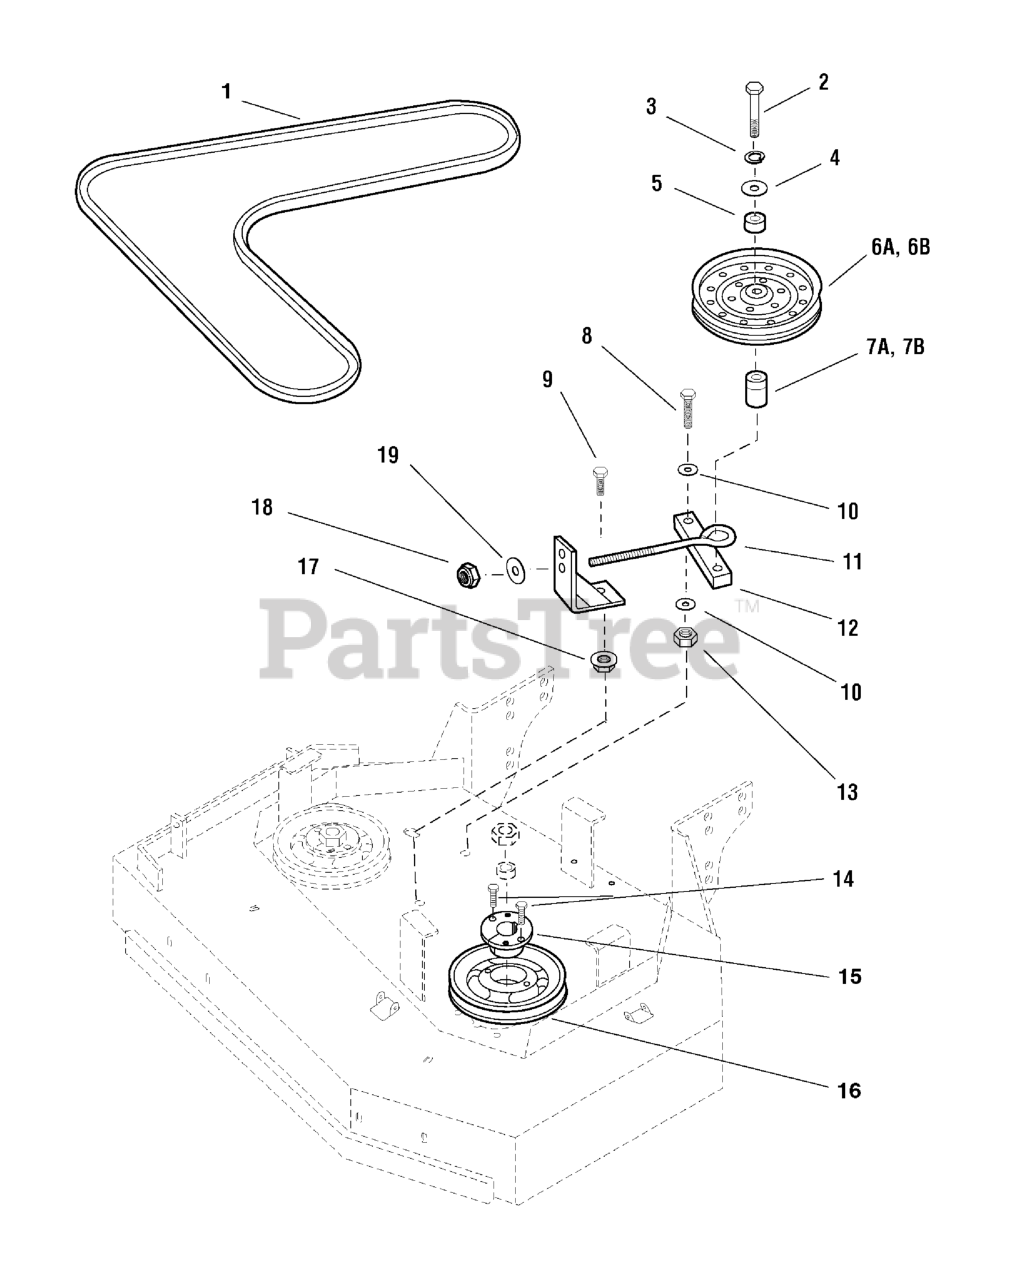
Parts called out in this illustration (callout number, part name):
1	BELT, Deck Drive
2	BOLT, 1/2-20 X 4" GD5 YZ
3	WASHER, 1/2" SPLIT LOCK
4	WASHER, 1/2 SAE
5	SPACER, .52 X 1.00 X .75, CZ
6A	PULLEY, Backside Idler
7A	SPACER, .52 X 1.00 X .88, PM, CZ
7B	SPACER, .52 x 1.00 x 1.63
8	BOLT, 7/16-20 X 1-3/4" GD.5
9	BOLT, 3/8-16 X 1" GD5 CZ
10	WASHER, 7/16" SAE
11	EYE BOLT, 3/8-16 X 8, 3THRD, 1EYE, CZ
12	ARM, Idler
13	NUT, 7/16-20 Hex Nylon Lock
14	BOLT, 1/4-20 X 1-1/4 GD5 CZ
15	BUSHING, Tapered Hub
16	PULLEY, Spindle
17	NUT, 3/8-16 Hex Large Serrated Flange
18	NUT, 3/8-16 HEX NYLON LOCK
19	WASHER, 3/8 SAE
